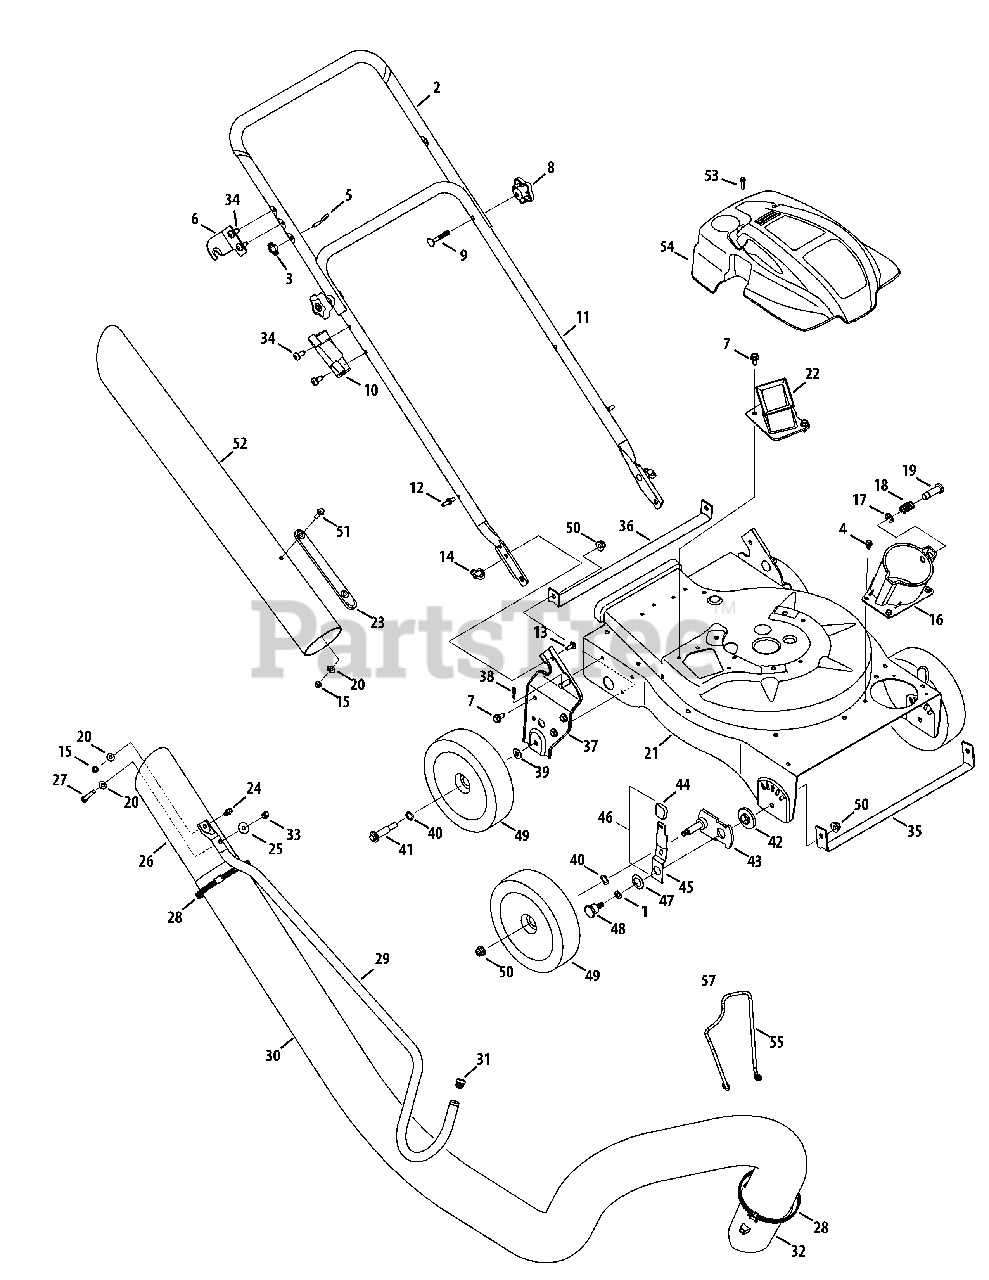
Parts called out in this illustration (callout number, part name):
1	Thrust Washer.375 ID x.70 OD
4	Screw, 1/4-20 x .500
6	Upper Handle Bracket
7	Hex Cap Screw 5/16-12 x.750
9	Carriage Bolt
10	Nozzle Handle Clip
13	Carriage Screw 1/4-20 x.75
14	Wing Nut 1/4-20
15	Hex Lock Nut, 1/4-20
16	Hose Base Adapter Assembly
17	E Ring.500 Dia
18	Compression Spring
19	Clevis Pin
20	Flat Washer.271 ID x.630 OD
21	Upper Flail Housing
22	Chipper Chute Assembly
23	Chute Strap
26	Hose Nozzle
27	Hex Cap Screw 1/4-20 x 2.625
28	Adjustment Clamp
30	Vacuum Hose
31	Handle Plug
32	Hose Adapter, Briggs
32	Hose Adapter, 173CC
33	Cap Lock Nut, 1/4-20
34	TT Screw, 5/16-18 x .750
35	Front Wheel Support Brace
36	Rear Wheel Support Brace
37	Handle Bracket Ass’y RH
37	Handle Brkt Ass’y LH
38	Cotter Pin
39	Bell Washer.401 ID x.870 OD
40	Wave Washer.531 ID x.781 OD
41	Shoulder Screw 3/8-16
42	Height Adjustment Bearing
43	Pivot Arm Assembly
44	Height Adjustment Knob
45	Spring Lever
46	Height Lever Assembly
47	Bell Washer.760 ID x.25 OD
48	Shoulder Screw,.750 x.500
49	Wheel 8 x 2
50	Flange Lock Nut, 3/8-16
51	Screw, 1/4-20 x .75
52	Hose Extension
53	Screw, #12-16 x 1.00
54	Engine Shroud
55	Tube Holder
